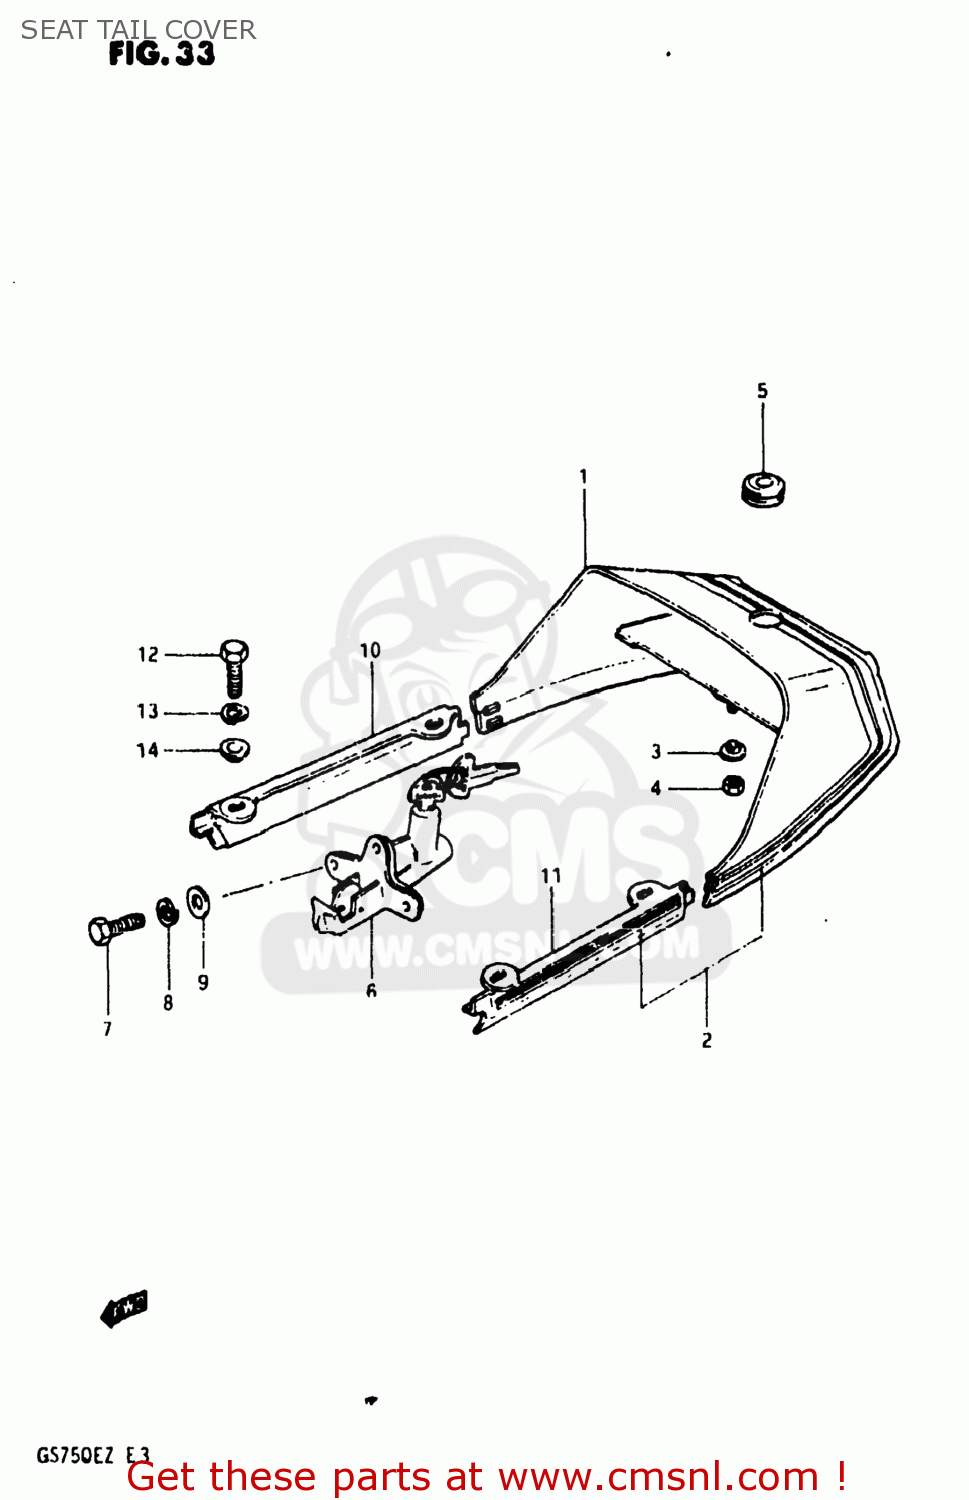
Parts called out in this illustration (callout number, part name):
1	COVER SET,SEAT TAIL
2	TAPE SET,SEAT TAIL COVER
3	WASHER
4	NUT 6MM
5	GROMMET,SEAT LOCK HOLE
6	LOCK SET,SEAT
7	BOLT
8	LOCK WASHER
9	WASHER 6MM
10	MOLDING,SEAT
11	MOLDING,SEAT
12	BOLT
13	LOCK WASHER
14	WASHER
